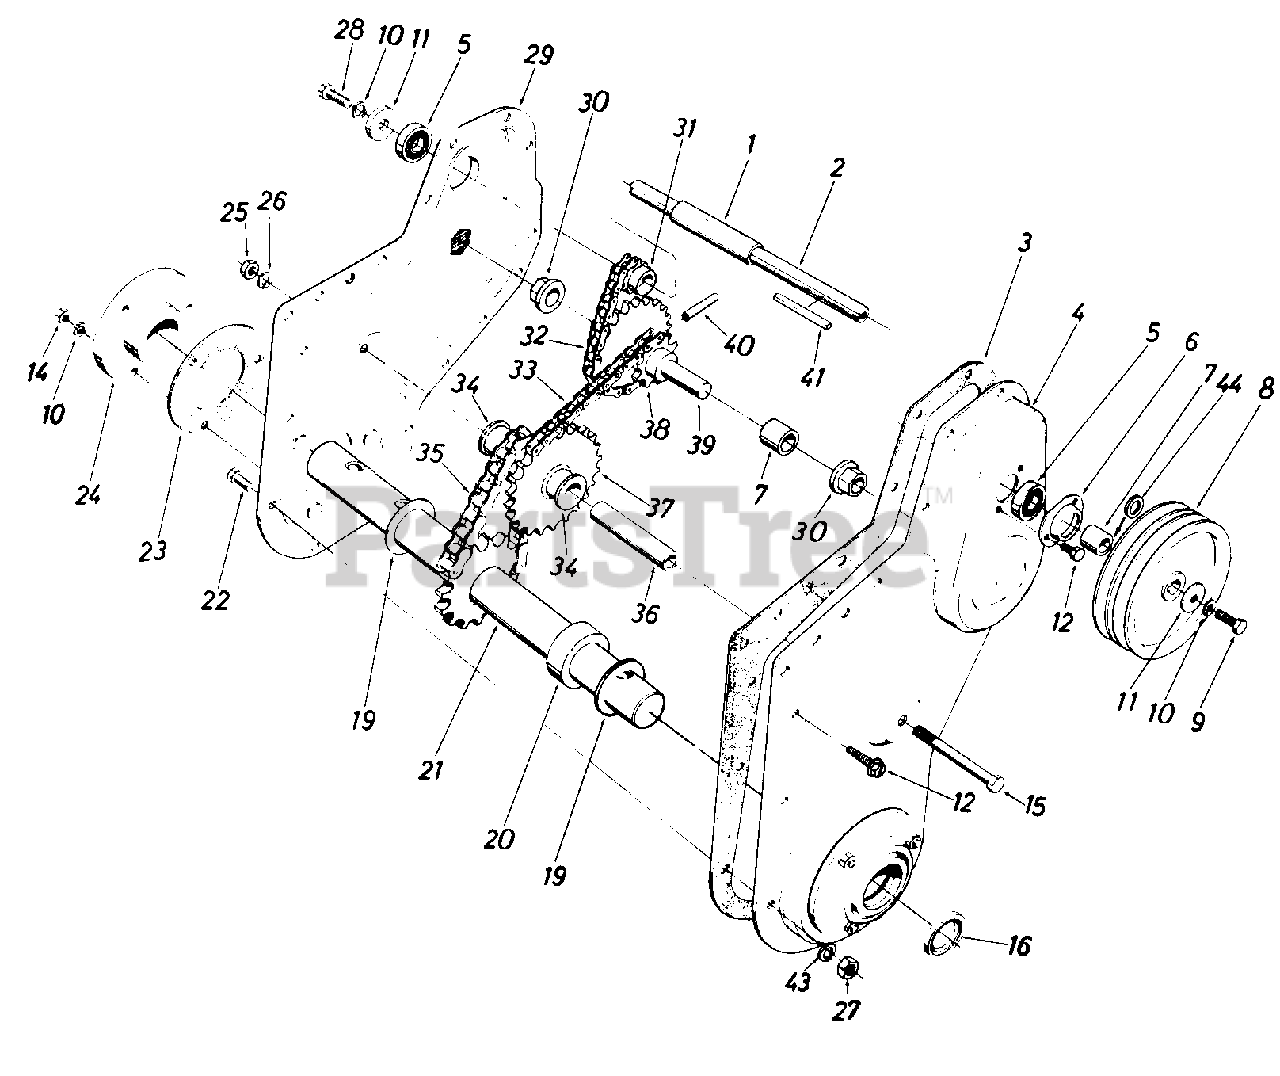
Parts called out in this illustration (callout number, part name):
1	Spacer .657 I.D. x .78 O.D.
2	Jack Shaft
3	Gasket for Housing
4	Housing Half-L.H.
5	Ball Bearing .625 I.D. x 1.375 O.D.
6	Bearing Housing
7	Spacer .625 I.D. x .88 O.D.
8	Transmission Pulley 6" Dia.
9	Hex Bolt 5/16-18 x 1.0" Lg. Special
10	L-Wash. 5/16" l.D.
11	Fl-Wash. 5/16 I.D. x 1.125 O.D. x .125
12	Hex Self-Tap Scr. 1/4-20 x 50" Lg
14	Hex Nut 5/16-18 Thd.
15	Hex Bolt 3/8-16 x 8 25n Lg.
16	Oil Seal 1" I.D. x 1.357 O.D.
19	Thrust Wash. 1.03 I.D. x 1.62 O.D.
20	Spacer 1.0" l.D. x 2.0" O.D.
21	Tine Shaft Ass'y.
22	Hex Bolt 1/4-28 x .62 Lg.
23	Gasket for Bearing Hgs.
24	Bearing Housing Ass'y.
25	Hex Nut 3/8-16 Thd.
26	L-Wash. 3/8" I.D.
27	Hex Nut 1/4-28 Thd.
28	Hex Bolt 5/16-18 x .62" Lg. Special
29	Housing Half-R.H.
30	Hex Flanged Bearing
31	Sprocket 10 Teeth x .500 Pitch
32	#41 Chain 1/2" Pitch x 34 Links-Endless
33	#420 Chain 1/2" Pitch x 48 Links-Endless
34	Flange Bearing .626 I.D.
35	#50 Chain 5/8" Pitch x 28 Links-Endless
36	Sprocket Shaft
37	Sprocket Brg. Sleeve Ass'y.
38	Sprocket Sleeve Ass'y.
39	Sprocket Shaft
40	Spring Pin Spiral 1.5" Lg.
41	Sq. Key 3/16 x 1.50" Lg.
43	L-Wash. 1/4n l.D.
44	Fl-Wash. .635" I.D. x 1.25 O.D.
